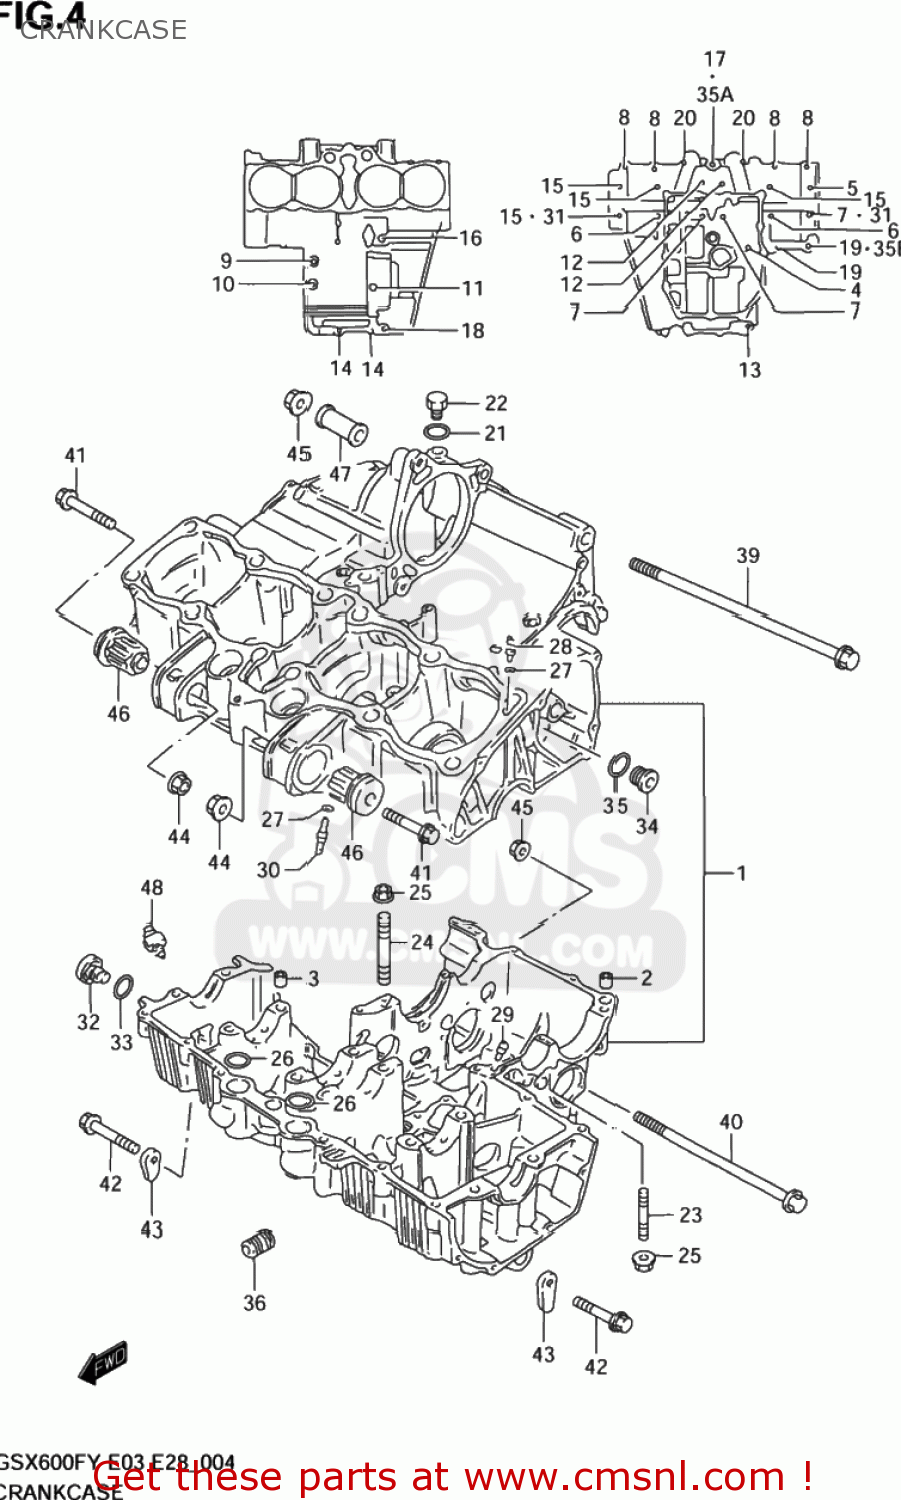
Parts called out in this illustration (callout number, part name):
1	CRANKCASE SET
2	PIN(10.4X13X22)
3	PIN(8.4X11X20)
4	BOLT(6X105)
5	BOLT(8X105)
6	BOLT(8X125)
7	BOLT(8X115)
8	BOLT
9	BOLT
10	BOLT,CL.COVER
11	BOLT
12	BOLT
13	BOLT
14	BOLT
15	BOLT(8X95)
16	BOLT
17	BOLT
18	BOLT
19	BOLT, HYDRAULIC UNIT NO.2
20	BOLT
21	GASKET(12.1X16.2X3.7) (NAS)
22	PLUG(12X9)
23	STUD BOLT
24	STUD BOLT
25	NUT
26	O RING(D:2.5,ID:21)
27	O RING(D:1.2,ID:4)
28	JET,AIR
29	JET
30	JET(13)
31	GASKET(8.5X17X2.3) (NAS)
32	PLUG
33	O RING(D:2.4,ID:16.8)
34	PLUG
35	GASKET(5.8X13X1.2) (NAS)
36	UNION,OIL STAND
37	PLATE,CRANK THRUST
38	PLATE,CRANK THRUST
39	BOLT(10X175)
40	BOLT(10X130)
41	BOLT
42	BOLT(10X50)
43	NUT
44	NUT
45	NUT
46	BUSH,ENGINE MOUNTING
47	SPACER,ENGINE MOUNT(L27)
48	SWITCH ASSY,OIL PRESSURE
